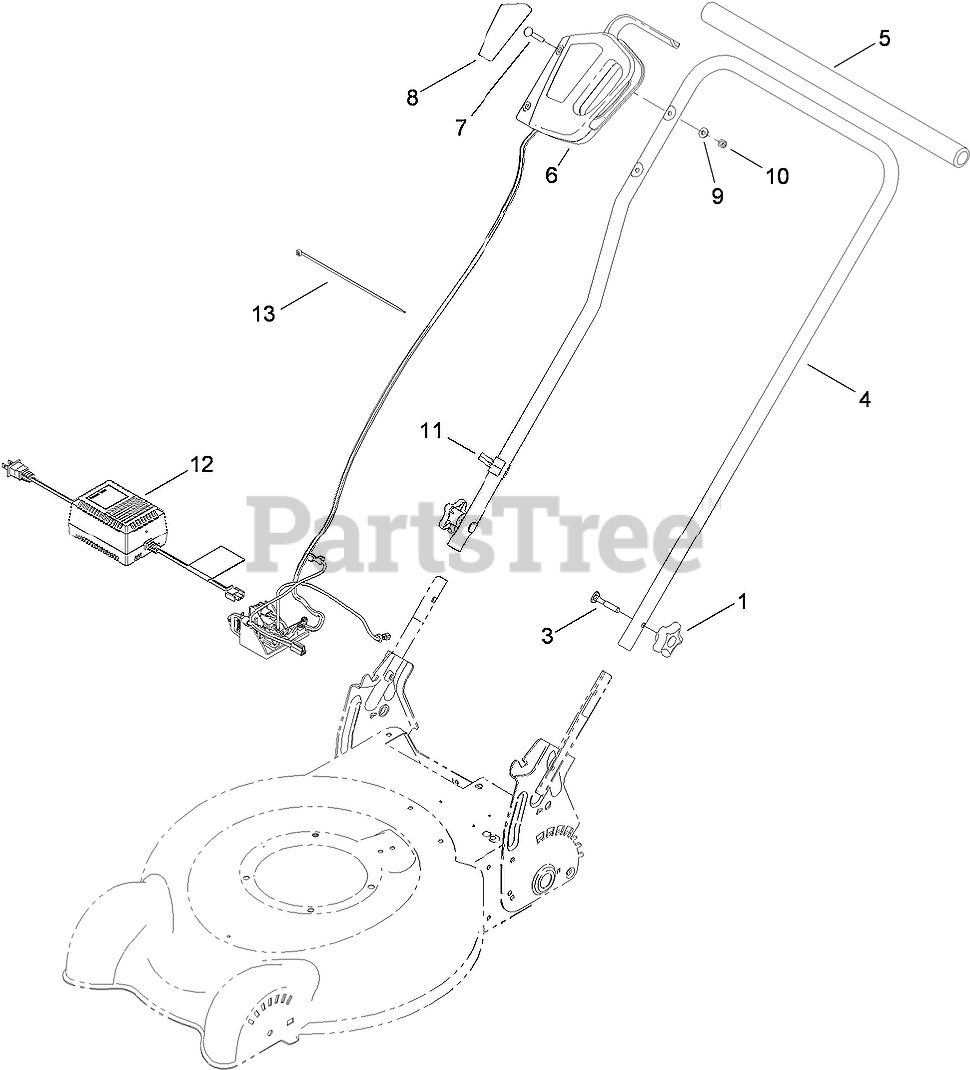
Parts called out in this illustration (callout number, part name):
1	KNOB-HANDLE
3	SCREW-HANDLE
5	FOAM-HANDLE
6	36 VOLT SWITCH ASM
7	SCREW-CARR
8	DECAL-HOUSING, SWITCH
9	WASHER-FLAT
10	NUT-LOCK, NI
11	GUIDE-CABLE
12	CHARGER-BATTERY
13	TIE-CABLE
